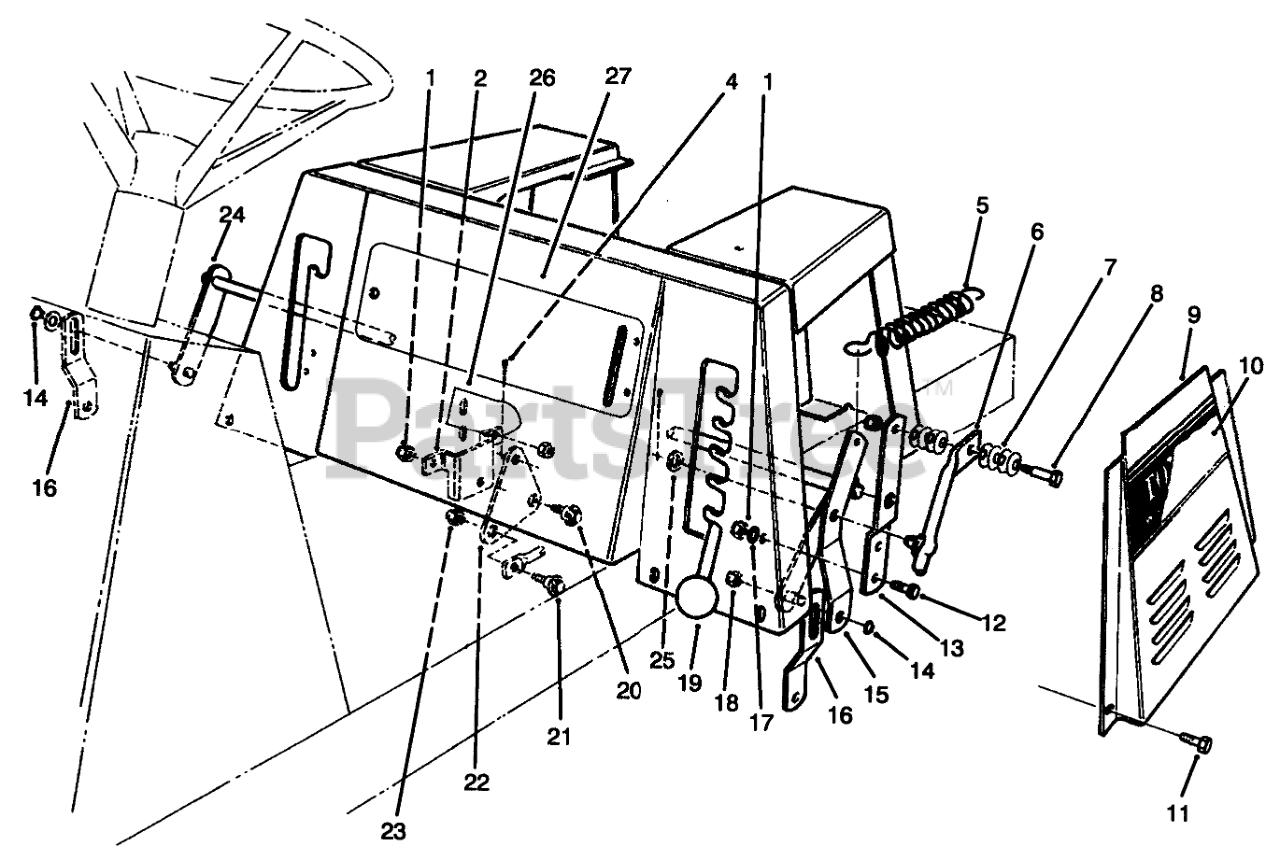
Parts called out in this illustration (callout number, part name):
1	NUT-LOCK, NI
2	BRKT-B.CRANK MTG
4	PIN-COTTER
5	SPRING-EXTENSION
6	HOC LEVER WA B
7	WASHER-BELLEVILLE
8	BOLT-SHOULDER
9	Panel L.H.-Base, Seat
10	DECAL - TORO 1232 LH
10	DECAL - TORO 1032 LH
11	SCREW-HH
12	SCREW-HH
13	Bracket
14	RING-RETAINING
15	Bracket-H.O.C., Engage
16	Link-Deck Suspension
17	WASHER-PLAIN
18	NUT-LOCK, NI
20	SCREW-SHOULDER
21	SCREW-SHOULDER
22	BELLCRANK
23	NUT-HEX
24	Arm
25	WASHER-FLAT
26	DECAL - USA
27	DECAL - CONTROL PANEL
